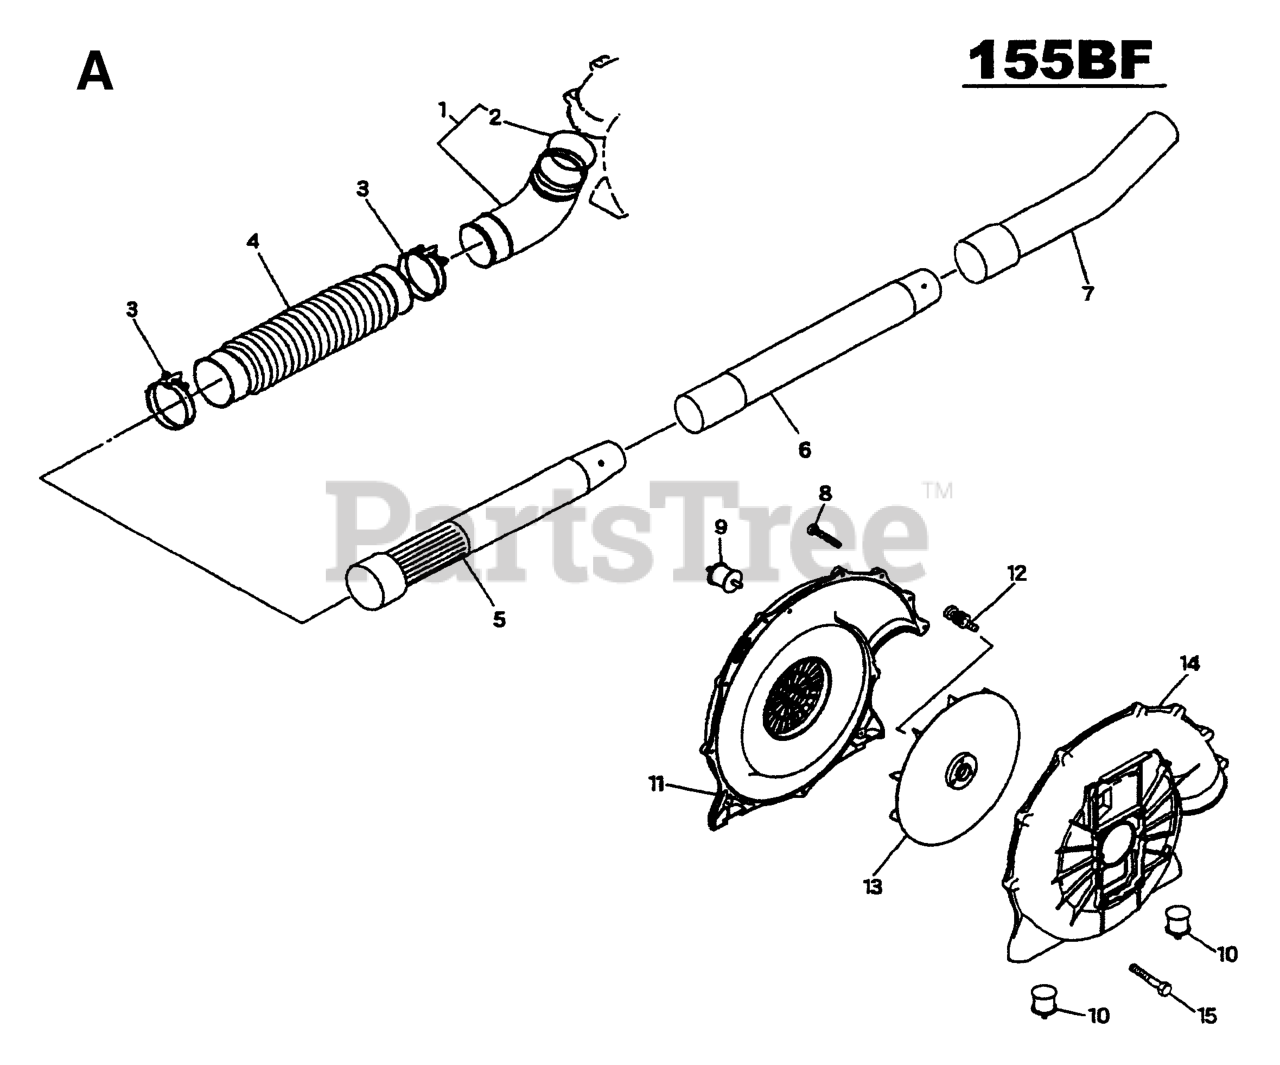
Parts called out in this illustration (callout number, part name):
1	ELBOW PIPE C.P.
2	O'RING
3	HOSE BAND
4	FLEX. PIPE 36084-101
5	BASE PIPE
6	MIDDLE PIPE
7	BEND PIPE
8	SCREW
9	ANTIVIBE MOUNT
10	ANTIVIBE MOUNT
12	BOLT
15	BOLT
